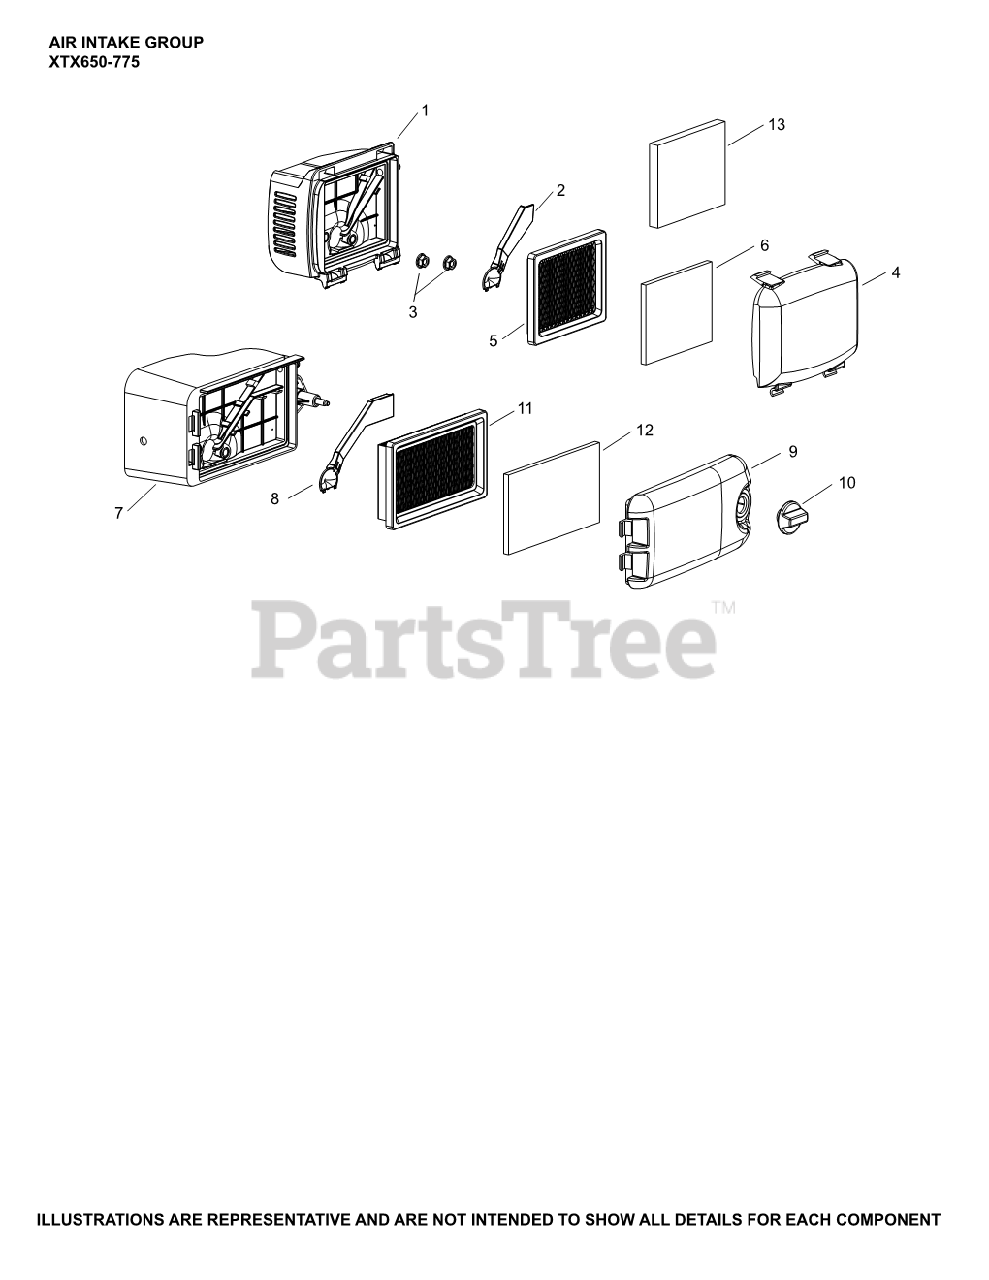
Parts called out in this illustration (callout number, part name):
7	KIT, AIR CLEANER BASE
8	COVER, A/C BASE (BREATHER GAS)
9	COVER, AIR CLEANER
10	KNOB USE 14 341 07-S
11	ELEMENT, AIR CLEANER USE 14 083 19-S
12	ELEMENT, PRE-CLEANER
